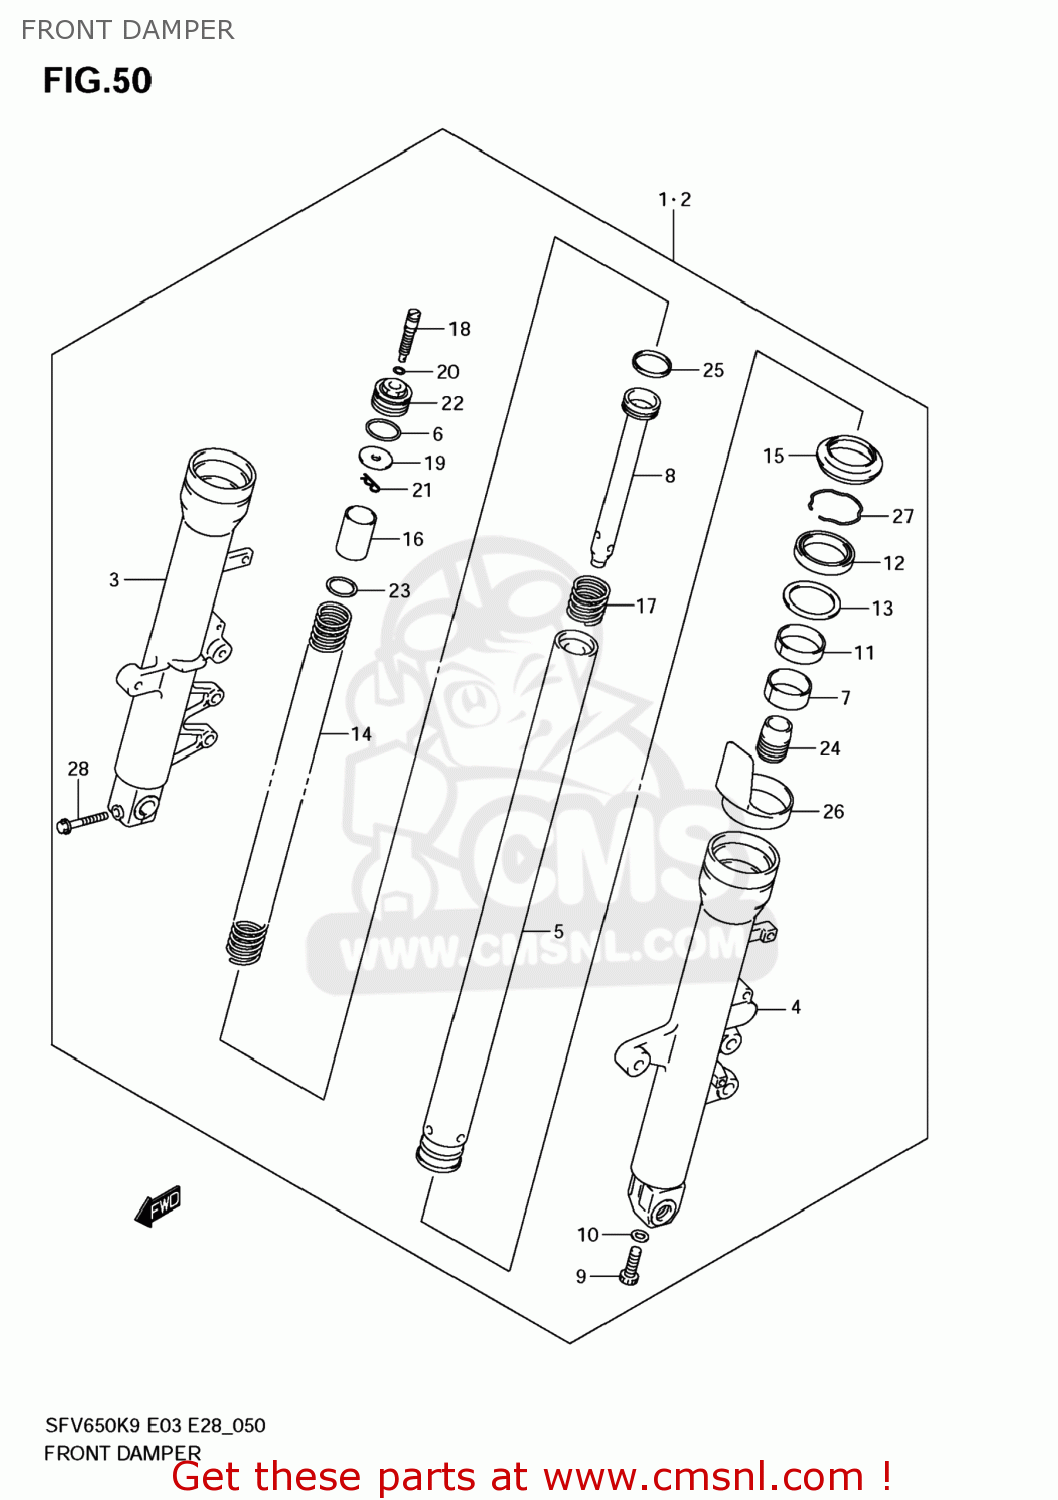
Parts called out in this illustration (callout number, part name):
1	DAMPER ASSY,FR FORK,R
2	DAMPER ASSY,FR FORK,L
3	TUBE,OUTER,R
4	TUBE,OUTER,L
5	TUBE,INNER
6	O RING
7	BUSH,SLIDE
8	CYLINDER
9	BOLT(8X27)
10	GASKET (NAS)
11	BUSH,GUIDE
12	SEAL,OIL
13	SPACER,SEAL
14	SPRING,FR
15	SEAL,DUST
16	COLLAR,SPRING(32.9X34X50)
17	SPRING,REBOUND
18	ADJUSTER BOLT,SPRING
19	SEAT,SPRING
20	O RING(D:1.9,ID:8.6)
21	PIN,SEAT SPRING
22	BOLT,FORK
23	JOINT,SPRING
24	PIECE,OIL LOCK
25	RING,PISTON
26	PROTECTOR
27	CIRCLIP,FORK OIL SEAL
28	BOLT
